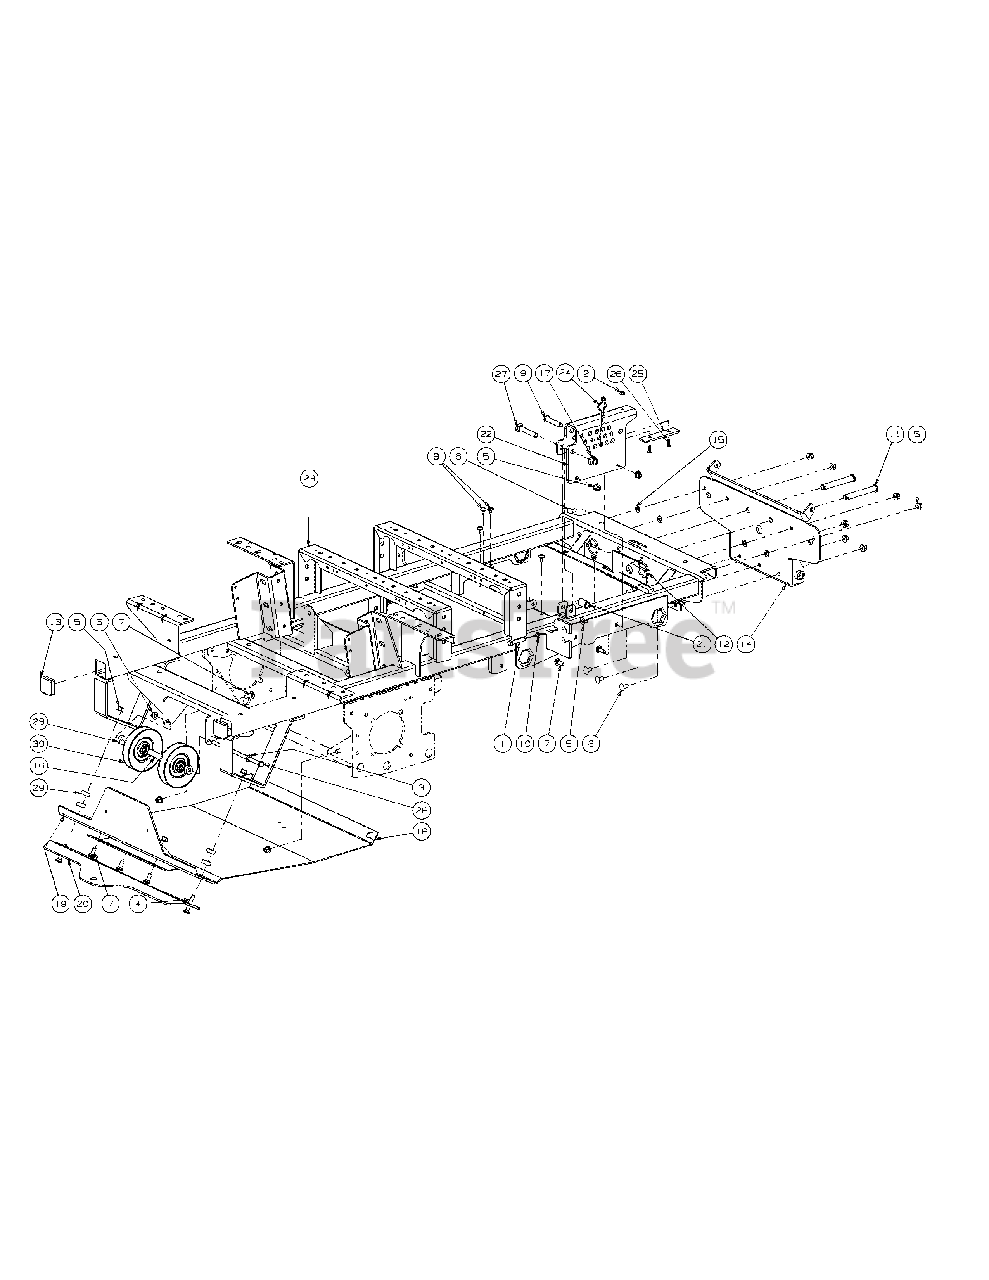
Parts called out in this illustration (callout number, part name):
1	Hex Cap Screw 3/8-16 x 2.00
2	Lock Nut w/Nylon Insert
3	Flat Washer, 3/8
4	Carriage Bolt, 3/8-16 x 2.00
5	Hex Nut, 3/8-16 Flange Lock
6	Carriage Bolt, 3/8-16 x .75 Long
7	Carriage Bolt, 3/8-16 x 1
8	Rubber Bumper, .62 OD x .22 Thick
9	Clevis Pin, .500 Dia. x 2.50 Lg.
10	Nut, 3/8-16, Jam
11	Clevis Pin, .625 Dia x 4.375 Long
12	Linch Pin, 3/16 Dia.
13	Plug, Square Tube
14	Bracket Assembly, Frame, Front
15	Push Retainer, 3/8"-Thread Stud
16	Spacer, .385 ID x .625 OD x 4.89
17	Nut, 1/2-13, Flangelock
19	Guard Bracket
21	Spacer, .51 ID x .75 OD x 1.40
22	Lift Index Bracket
23	Frame Assembly
24	HitchPin, .120 Dia. x 3.0
25	Wear Plate, 1.125 x 5.00
26	Flat Head Cap Screw, 1/4-20 x .75
27	Carriage Bolt, 1/2-13 x 3.00
28	Hex Head Cap Screw, 3/8-16 x 8.50
29	Spacer .406 ID x 1.0 OD
30	Idler Pulley, 5.06 Dia.
